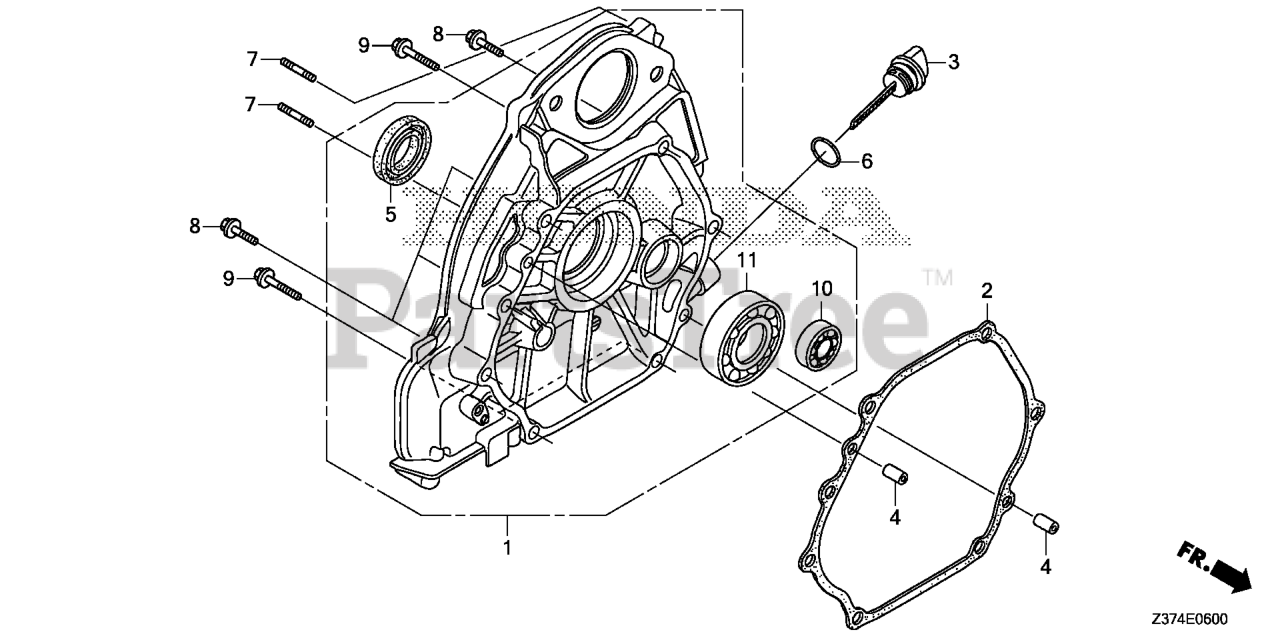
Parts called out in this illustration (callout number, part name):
1	COVER ASSY., CRANKCASE
2	GASKET, CRANKCASE COVER
3	CAP, OIL FILLER
4	PIN, DOWEL (8X12)
5	OIL SEAL (35X52X8)
5	OIL SEAL (35X52X8) (NOK)
6	O-RING (26X2.7)
7	BOLT, STUD (8X55)
8	BOLT, FLANGE (8X40)
9	BOLT, FLANGE (8X60)
10	BEARING, RADIAL BALL (6202)
11	BEARING, RADIAL BALL (6207)
